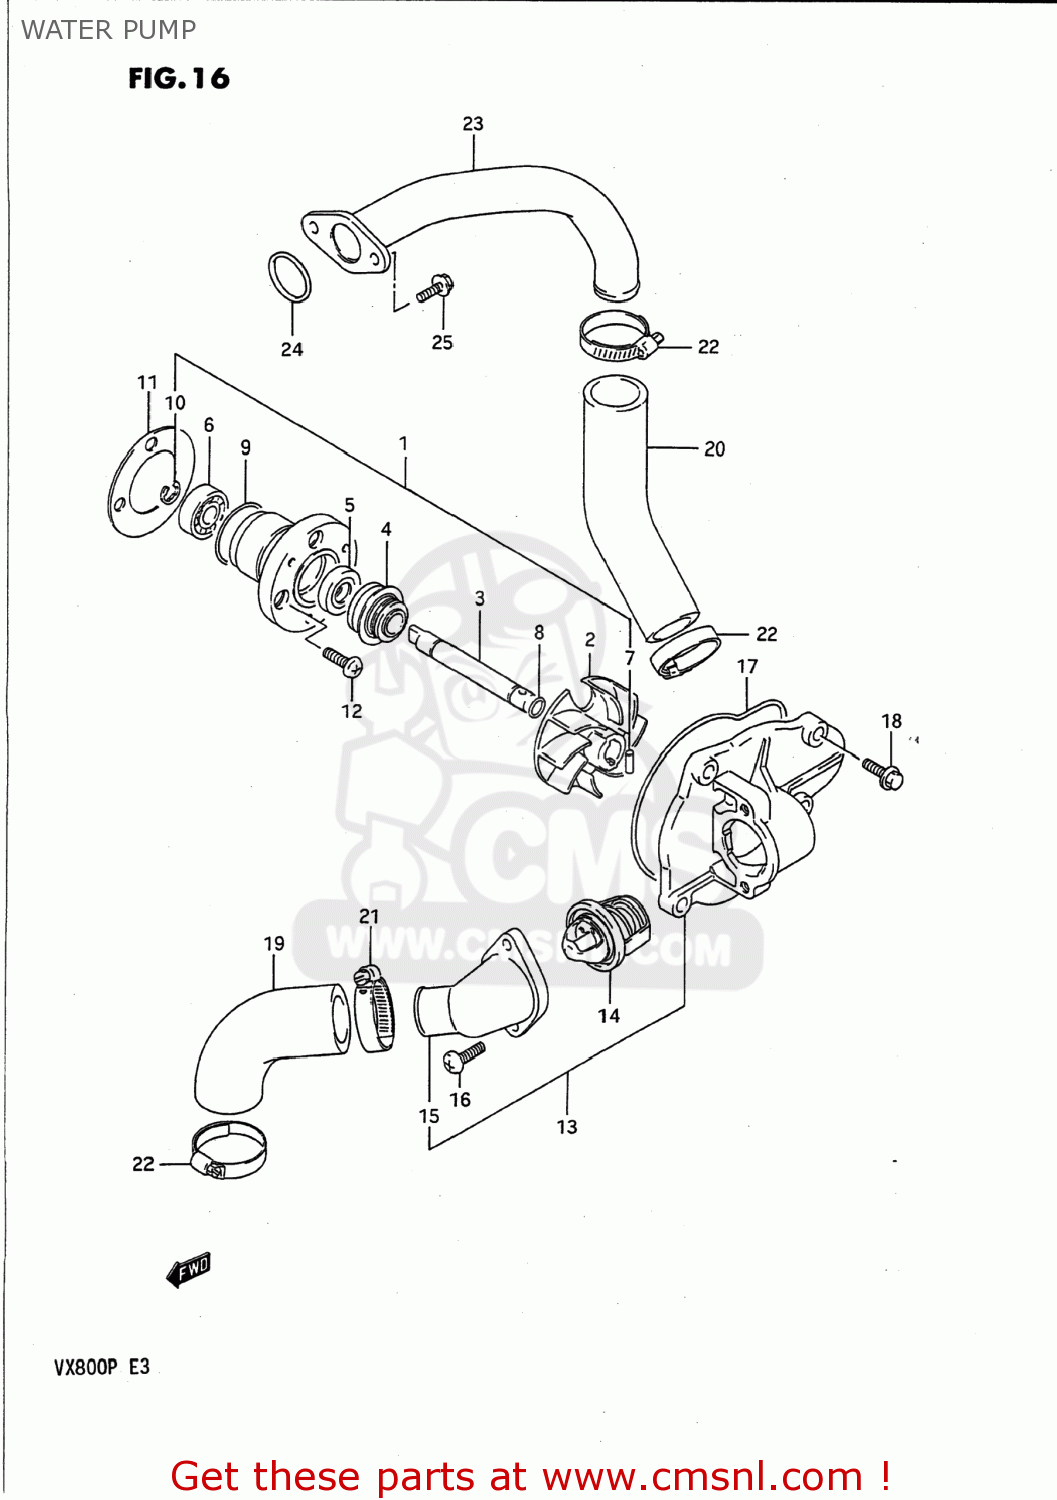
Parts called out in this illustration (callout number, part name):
1	PUMP ASSEMBLY,WATER
2	IMPELLER
3	SHAFT
4	SEAL,MECHANICAL
5	OILSEAL
6	BEARING,10X26X8
7	PIN
8	O RING
9	O RING
10	E RING
11	GASKET,WATER PUMP (NAS)
12	SCREW
13	CAP ASSY,WATER PUMP
14	THERMOSTAT,WATER
15	CONNECTOR
16	SCREW
17	O RING,WATER PUMP CAP
18	BOLT
19	HOSE,WATER PUMP IN
20	HOSE,WATER
21	CLAMP
22	CLAMP
23	PIPE,CYLINDER INLET
24	O RING(D:2.3,ID:24.4)
25	BOLT
